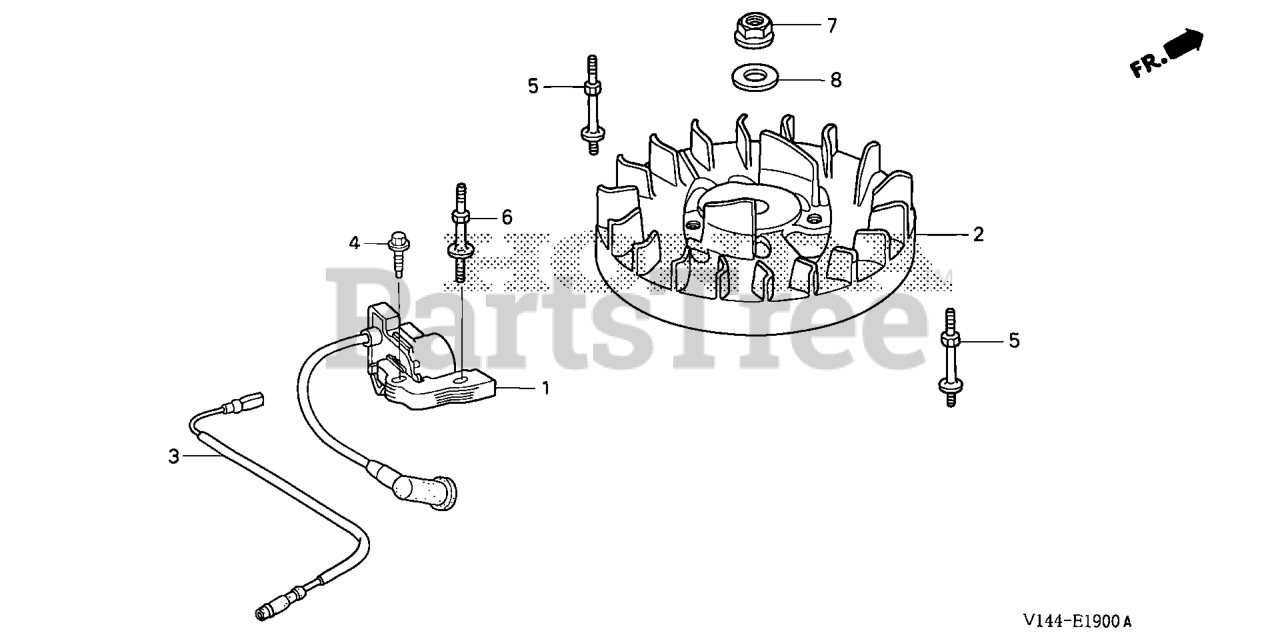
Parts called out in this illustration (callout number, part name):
1	COIL ASSY., IGNITION
3	WIRE, STOP SWITCH
4	BOLT, FLANGE (5X20)
5	BOLT, STUD A
6	BOLT, STUD B
7	NUT, FLANGE (10MM)
8	WASHER, PLAIN (10MM)
